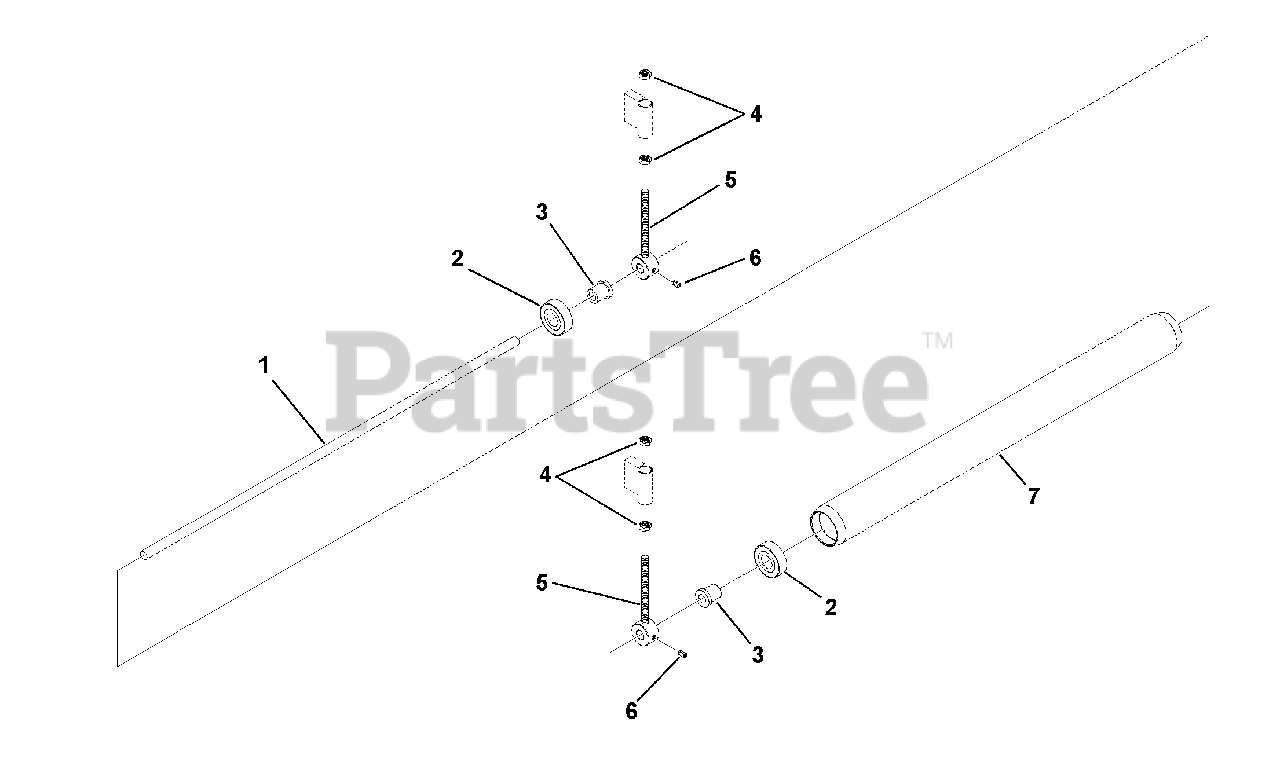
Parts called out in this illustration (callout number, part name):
1	Shaft, Front Roller 25-Inch (995310)
2	Bearing, 47 mm x 20 mm x 14 mm
4	Nut, Jam .50-13
5	Weldment, Front Roller Adjustment Rod
6	Set Screw, Square Head Cup Point .25 x .50
7	Roller, Height 25-Inch (995310)
